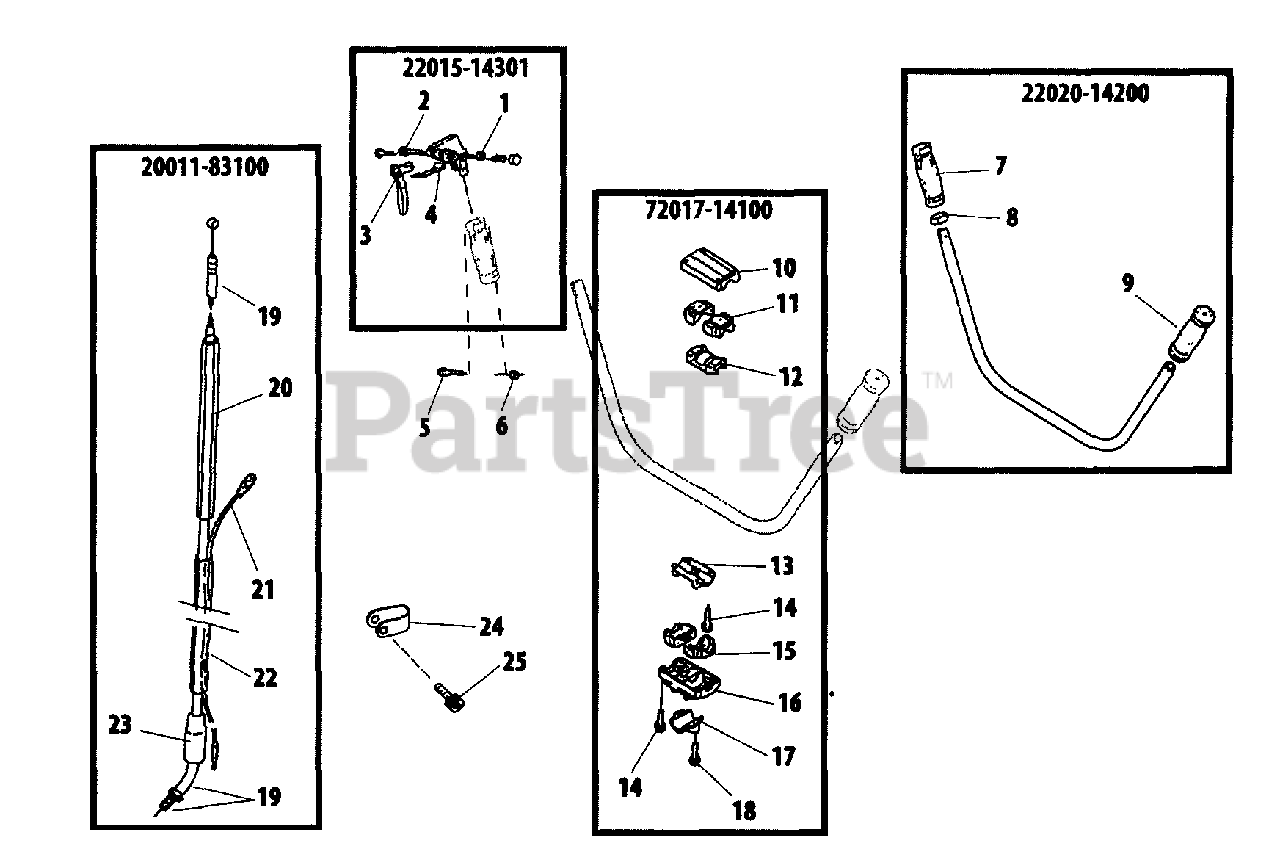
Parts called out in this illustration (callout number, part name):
1	LOCKNUT - 5
2	BOLT
3	TRIGGER, THROTTLE
4	THROTTLE LEVER STOPPER
5	SCREW - 4X24
6	NUT - 4 -- NYLON
7	GRIP - RIGHT
8	HOLDER, CABLE
9	GRIP - LEFT
10	CAP - UPPER
11	CUSHION - UPPER
12	CLAMP - UPPER
13	CLAMP - LOWER
14	SCREW - 5X25
15	CUSHION - LOWER
16	BRACKET, HANDLE
17	SPACER
18	SCREW - 6X25
19	CABLE, THROTTLE
20	TUBE, PROTECTIVE
21	WIRE
22	TUBE, PROTECTIVE
23	CAP, DUST
24	CLAMP, CABLE
25	SCREW - 4X12
20011-83100	THROTTLE CONTROL ASSY
22015-14301	THROTTLE CONTROL ASSY
22020-14200	HANDLE ASSY
72017-14100	HANDLE BRACKET KIT
